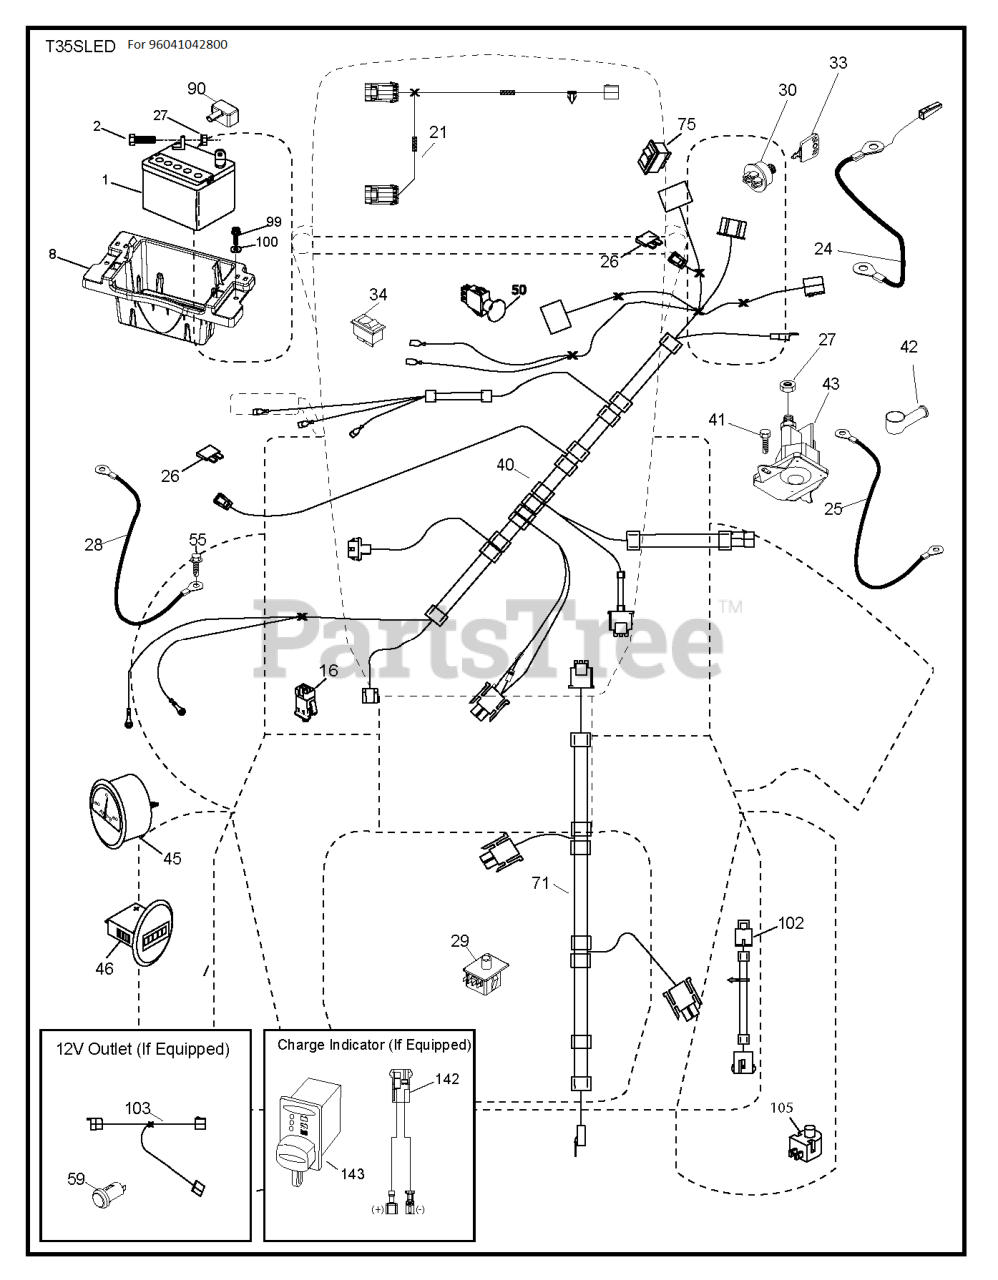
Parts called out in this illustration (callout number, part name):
1	BATTERY.DRY.30.AMP
2	BOLT.HEX.1/4.X.3/4.DICHROMATE
8	TRAY.BATTERY BOX.FRONT
16	SWITCH INTERLOOK PUSH-IN
21	HARNESS LIGHT ASSY TRACTOR,
24	CABLE.FRBATT.W/WIRE.8GA.8
25	CABLE.STARTER.8GA.17.5
26	FUSE 20AMP
28	CABLE.GROUND.21"BLK.8GA.90T
29	SWITCH.SEAT.DP W/RAMPS
30	SWITCH.IGN.DELTA.W.LGH.ROS
33	KEY.CHAIN.BLISTER.PACK.GEN.INT
40	HARNESS.DASH.EDIFF.RND.CHG
42	COVER.TERMINAL.RED
50	SWITCH.PTO.8TERMINAL.STD.BLK
55	BOLT.5/16-18UNCX3/4 W/SEMS.BLK
71	HARNESS.IGN.CHASSIS.TEX.DCKLOC
75	SWITCH.ON/OFF.(DIFF.LOCK)
90	COVER.TERMINAL.BATTERY
99	SCREW HEXWSHR 1/4-20X3/4
102	HARNESS PIGTAIL PCH TEX ROS
105	REVERSE SWITCH
